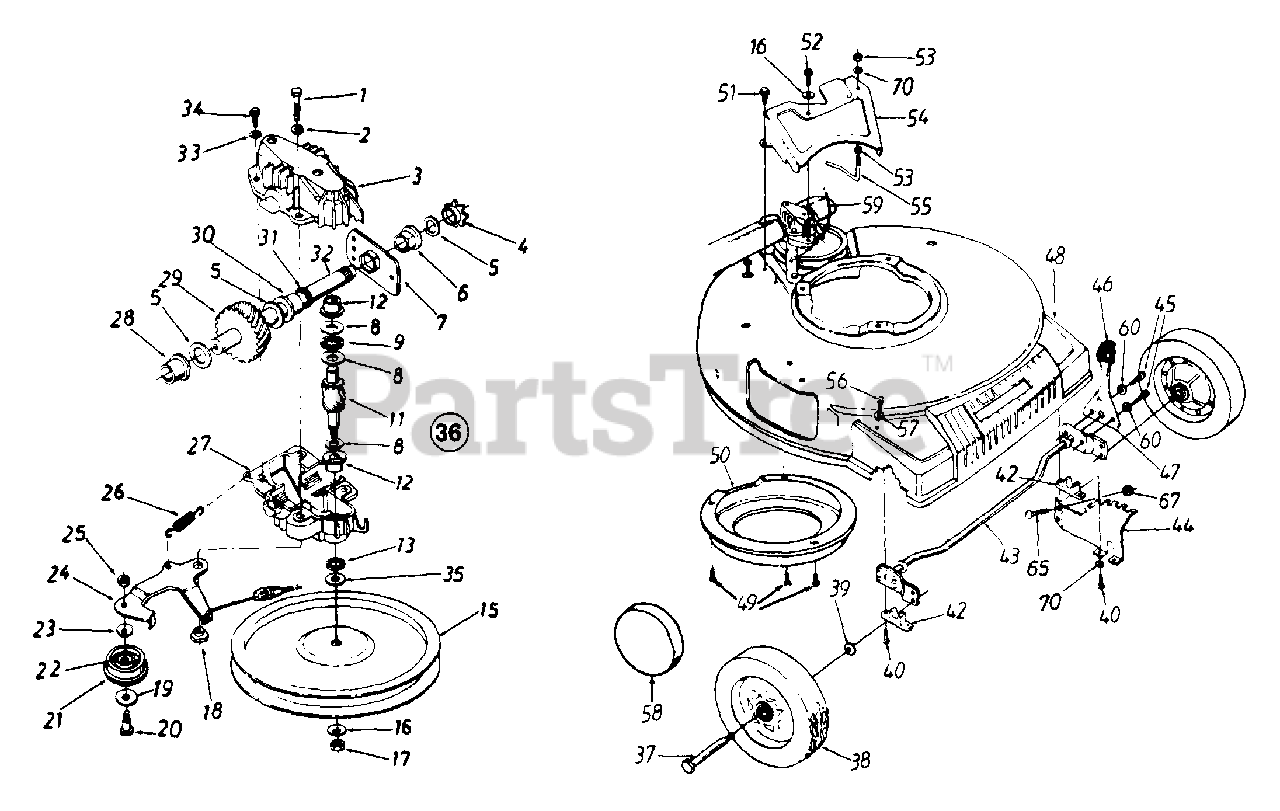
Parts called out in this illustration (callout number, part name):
1	Hex Patch Bolt 1/4-20 x 1.25"
2	L-Wash. 1/4" I.D.
3	Upper Hsg. Half
4	#48 Sprocket 7T x 1/2 Pitch
5	Fl-Wash. 5/8" I.D. x .030
6	Hex Flange Brg..631" I.D.
8	Thrust Wash..382" I.D. x .70" O.D.
9	Thrust Bearing .375" I.D. x .812" O.D.
11	11 Tooth Pinion Shafts
12	Flange Bearings
13	Oil Seals
15	Fl-Pulley 5.06" O.D.
16	Bell-Wash..265" I.D. x.75"
17	Hex L-Nut 1/4-28 L.H. Thd.
18	Shld. Spacer .375" Dia. x .170
19	Fl-Wash..390" I.D. x 1.0"
20	Shld. Bolt .375" Dia. x .40"
21	Fl-Idler Plastic 1.50" Dia.
22	Needle Brg..375" x .31
24	Idler Brk't. Ass'y.
25	Hex Patch L-Nut 1/4-28 Thd.
26	Extension Spring 1.12" Lg.
27	Lower Hsg. Half
28	Flange Bearing .566 Dia.
29	33 Tooth Helical Gear
30	Flange Bearing .629 Dia.
31	Oil Seal .625 Dia.
32	Gear Sprocket Shaft
33	L-Wash. #10 I.D.
34	Hex B-Tap Scr. #10 x .62"
35	Hex Washer .26" x .88"
36	Transmission Comp.
37	Front Axle Bolt
38	Wheel Ass'y. Comp.
39	Bell-Wash..380" I.D. x .88
40	Hex Wash. Hd. Scr. 1/4 x 1" Lg.
42	Block Bushing
45	Hex TT-Tap Scr. 1/4-20 x .38"
46	Knob
47	Spring Lever
48	Plastic Front End
49	Hex B-Tap Scr. 1/4" x .38"
52	Hex Wash. Hd. B-Tap Scr. 1/4 x .62"
53	Hex Nut 1/4-20 Thd.
56	Torx Truss Hd. Scr. 5/16 x .75"
57	Bell-Wash..345" I.D. x.88"
58	Hub Cap
59	S.P. Cable
60	External L-Wash. 1/4" I.D.
65	Carr. Bolt 1/4-20 x .5" Lg.
67	Hex Flange L-Nut 1/4-20 Thd.
70	L-Wash. 1/4" I.D.
